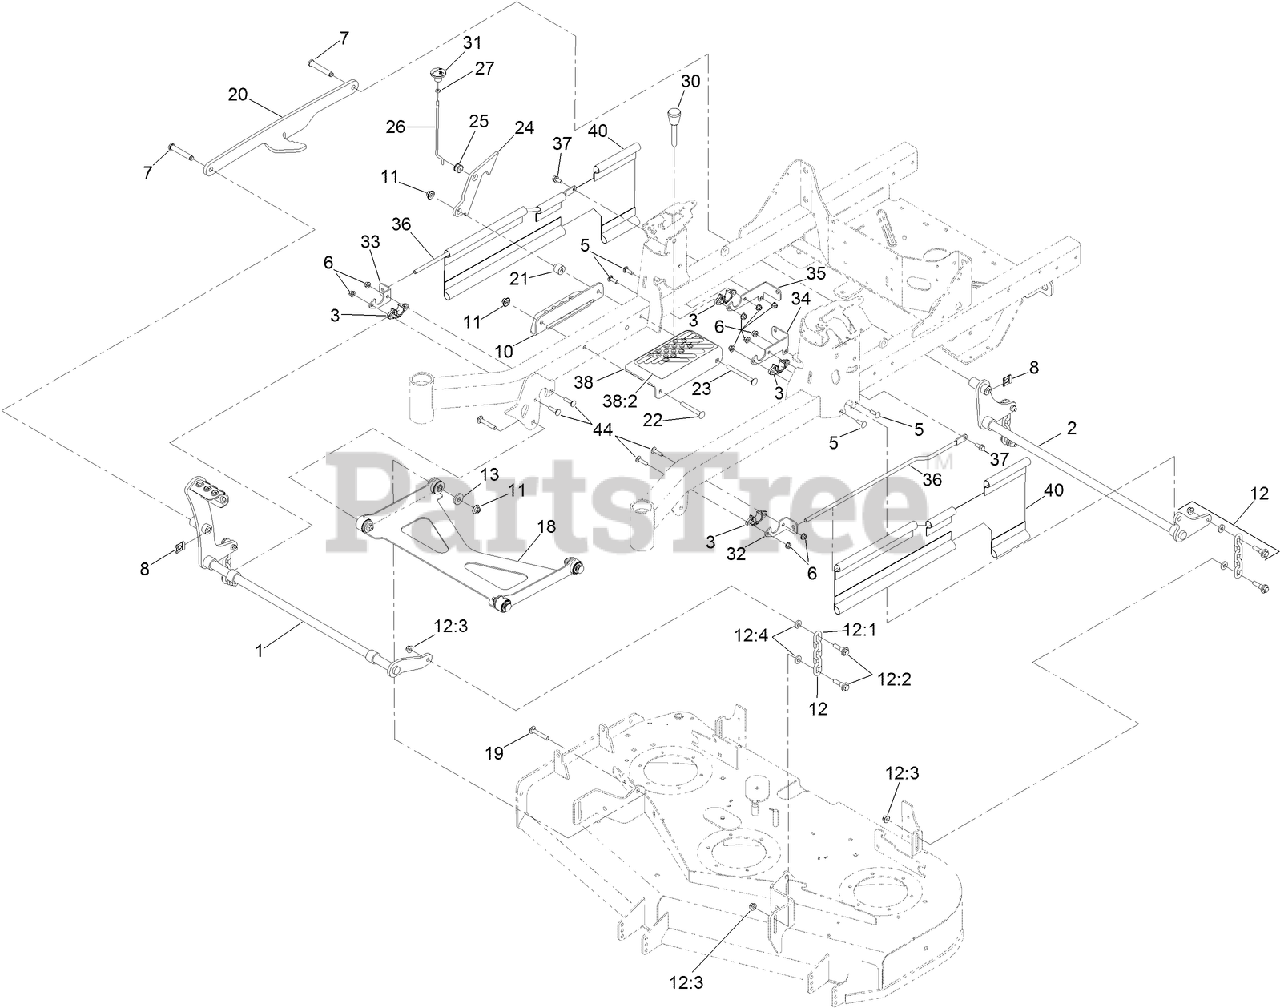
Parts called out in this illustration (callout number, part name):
1	SHAFT-LIFT, DECK
2	SHAFT-LIFT, DECK (REAR)
3	BUSHING-FLANGE
5	SCREW-CARR
6	NUT-HF, NI
7	PIN-CLEVIS
8	CLIP-PIN
10	ANGLE-HOC, LOWER
11	NUT-FLANGE, NI
12	DECK CHAIN ASM
12:1	CHAIN-LIFT, DECK
12:2	BOLT-SHOULDER
12:3	NUT-HF, NI
12:4	SPACER
13	WASHER
18	DECK STRUT ASM
19	SCREW-CARR
20	LINK-LIFT
21	SPACER-STEPPED
22	SCREW-CARR
23	SCREW-CARR
24	PLATE-LOCK, TRANSPORT
25	GROMMET
26	ROD-LOCK, TRANSPORT
27	NUT-JAM
30	PIN-HOC
32	BRACKET-MOUNT, FRONT (LH)
33	BRACKET-MOUNT, FRONT (RH)
34	BRACKET-MOUNT, UPPER REAR (LH)
35	BRACKET-MOUNT, UPPER REAR (RH)
36	ROD-SUPPORT, UPPER
37	SCREW-HHF
38	HOC PLATE W/DECAL
38:2	DECAL-HOC
40	GUARD-SIDE
44	SCREW-CARR
